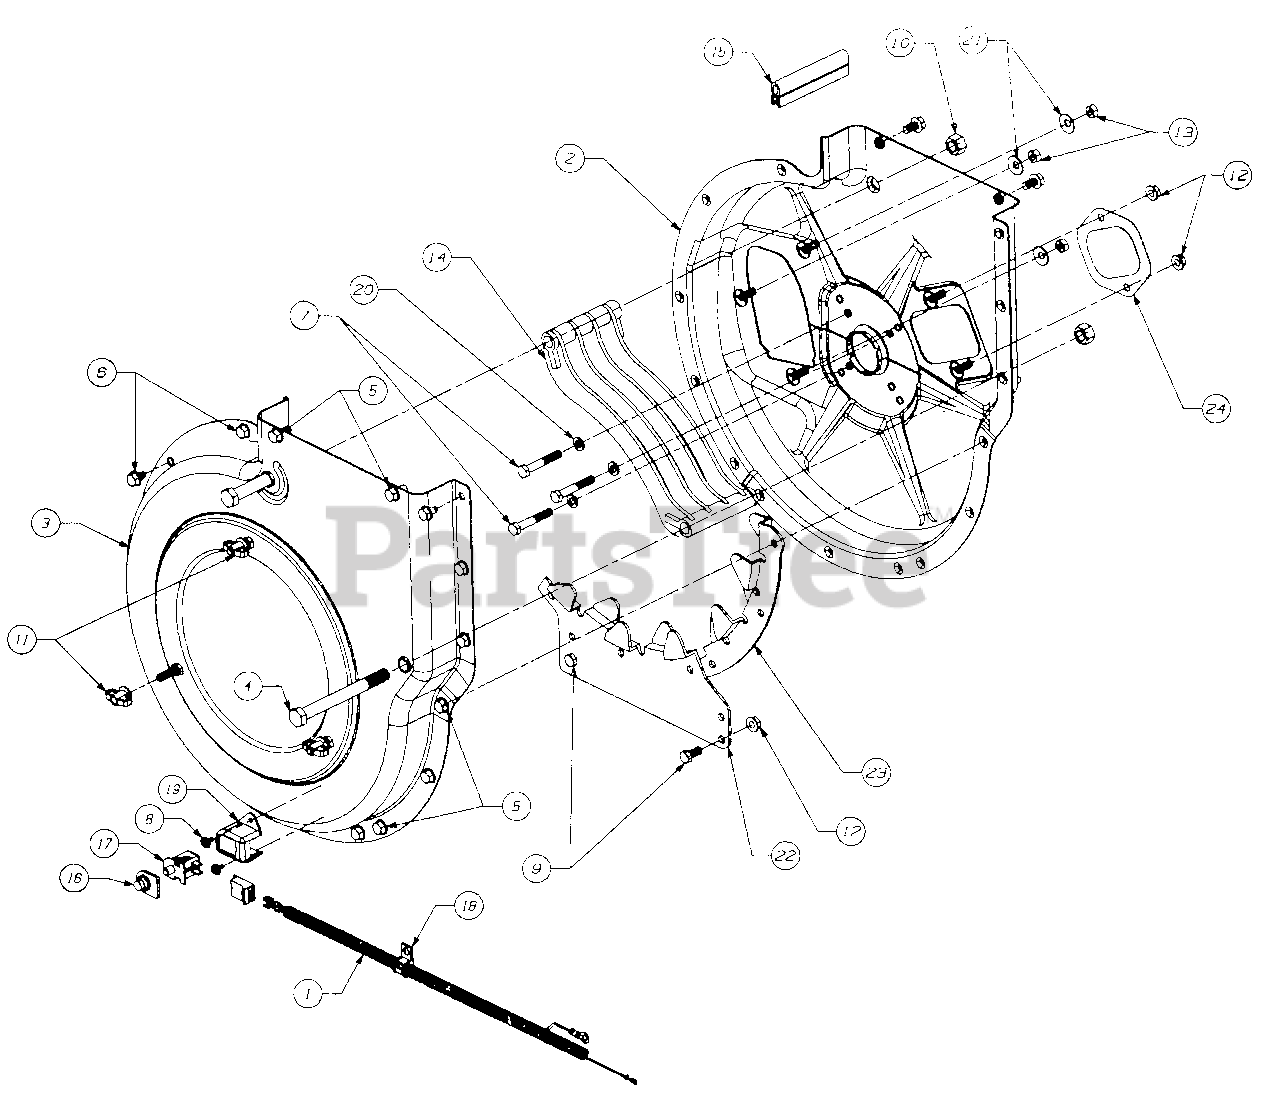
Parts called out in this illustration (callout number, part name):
1	HARNESS - CHIPPER-VAC
4	SCREW-HEX
5	SCREW-HEX SELF TAP
6	SCREW-HEX SELF TAP
7	SCREW-HEX
8	SCREW-HEX SELF TAP
9	SCREW-HEX
10	NUT-HEX LOCK
12	NUT-HEX LOCK
13	NUT-HEX (GR 5)
14	SCREEN
15	SEAL-RUBBER
16	COVER-SWITCH
17	SNAP MOUNT SWITCH
18	CLAMP
19	COVER-SWITCH
20	WASHER-LOCK
21	WASHER-BELL
